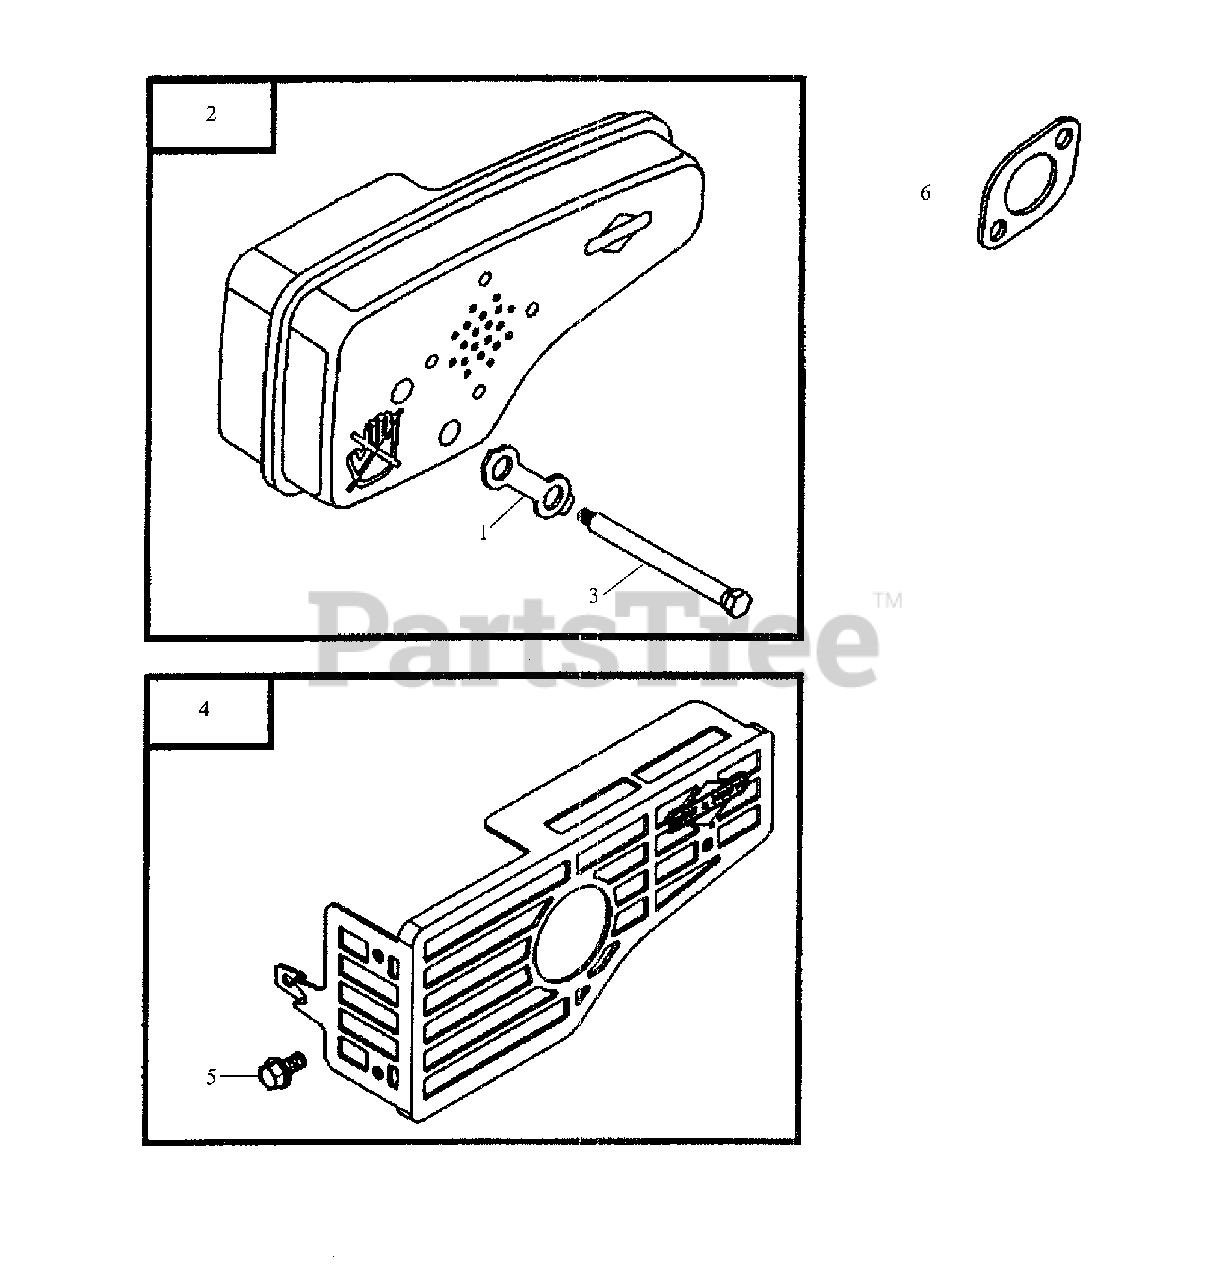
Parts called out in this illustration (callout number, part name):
1	Lock Tab
2	Muffler
3	Screw, Exhaust
4	Guard, Muffler
5	Screw, Muffler Guard
6	Gasket, Exhaust
